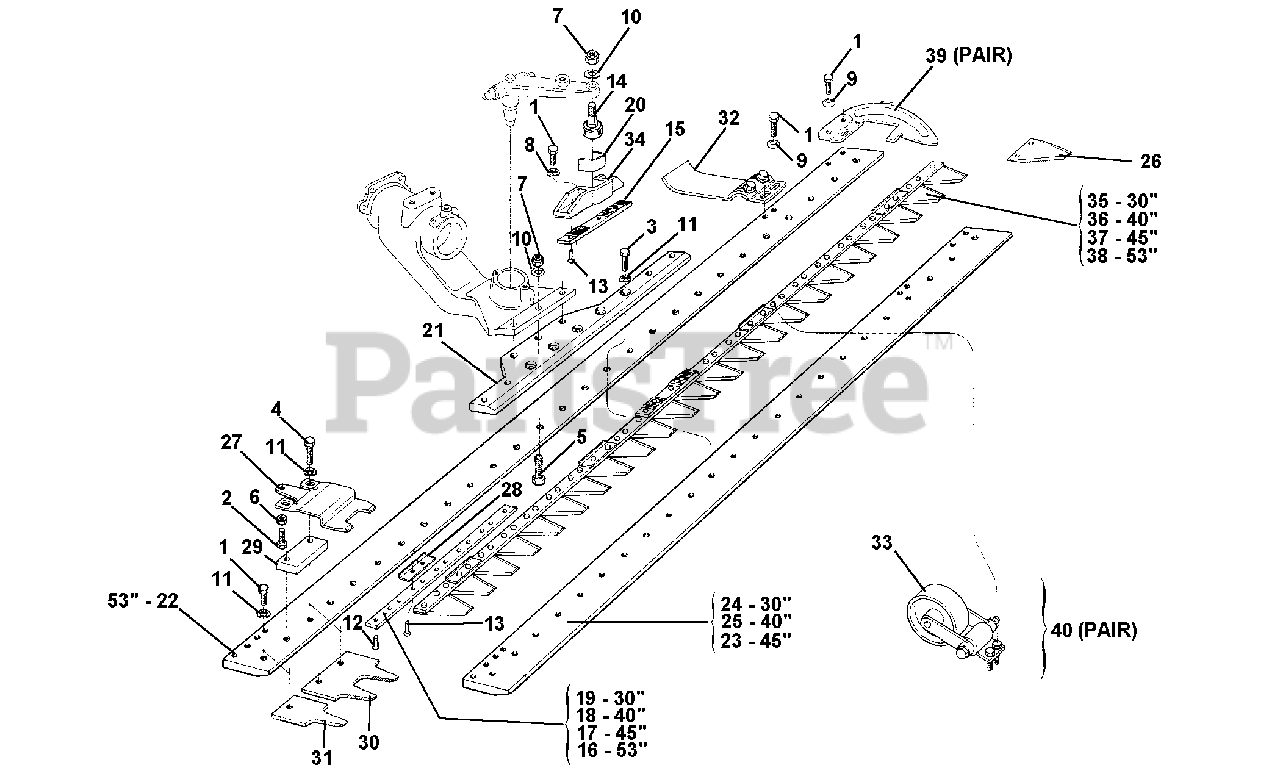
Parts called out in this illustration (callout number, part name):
1	SCREW M8 X 16
2	SCREW M8 X 20
3	SCREW M8 X 25
4	SCREW M8 X 35
7	SELF LOCKING NUT
8	WASHER, FLAT 8.4
9	SUPER WASHER 8 DIN 6796
10	SUPER WASHER 10 DIN 6796
11	WASHER, LOCK 8.4
12	RIVET TSV 6.5 X 13
13	RIVET TSV 6.5 X 16
14	BLADE CONTROL PIN
15	PLATE FOR BLADE COUPLING
16	STRIP FOR BLADE MT. 1.35
17	STRIP FOR BLADE MT. 1.15
18	BLADE STRIP
19	BLADE STRIP
21	BAR COUPLING
22	SLIDE FOR CUTTER BAR
24	SLIDE COMBO BAR, 0.80
25	SLIDE COMBO BAR 1.0 MT
26	SECTION F. NARROW SCORED BLADE
27	BLADE HOLDER
28	PLATE FOR CLEANING
29	BLADE GUIDE BLOCK
30	DOUBLE FINGER
31	SINGLE FINGER
32	SLIDE WITH SCREWS
33	WHEEL D = 100
34	BLADE CONNECTION
35	SCORED COMBO BLADE 0.80 M.
36	SCORED COMBO BLADE 1M.
37	SCORED CENTRAL BLADE 1.15 MT.
38	SCORED CENTRAL KNIFE 1.35
39	END GUARD-COMBO BAR (PR)
40	CUTTER BAR WHEELS - PAIR
